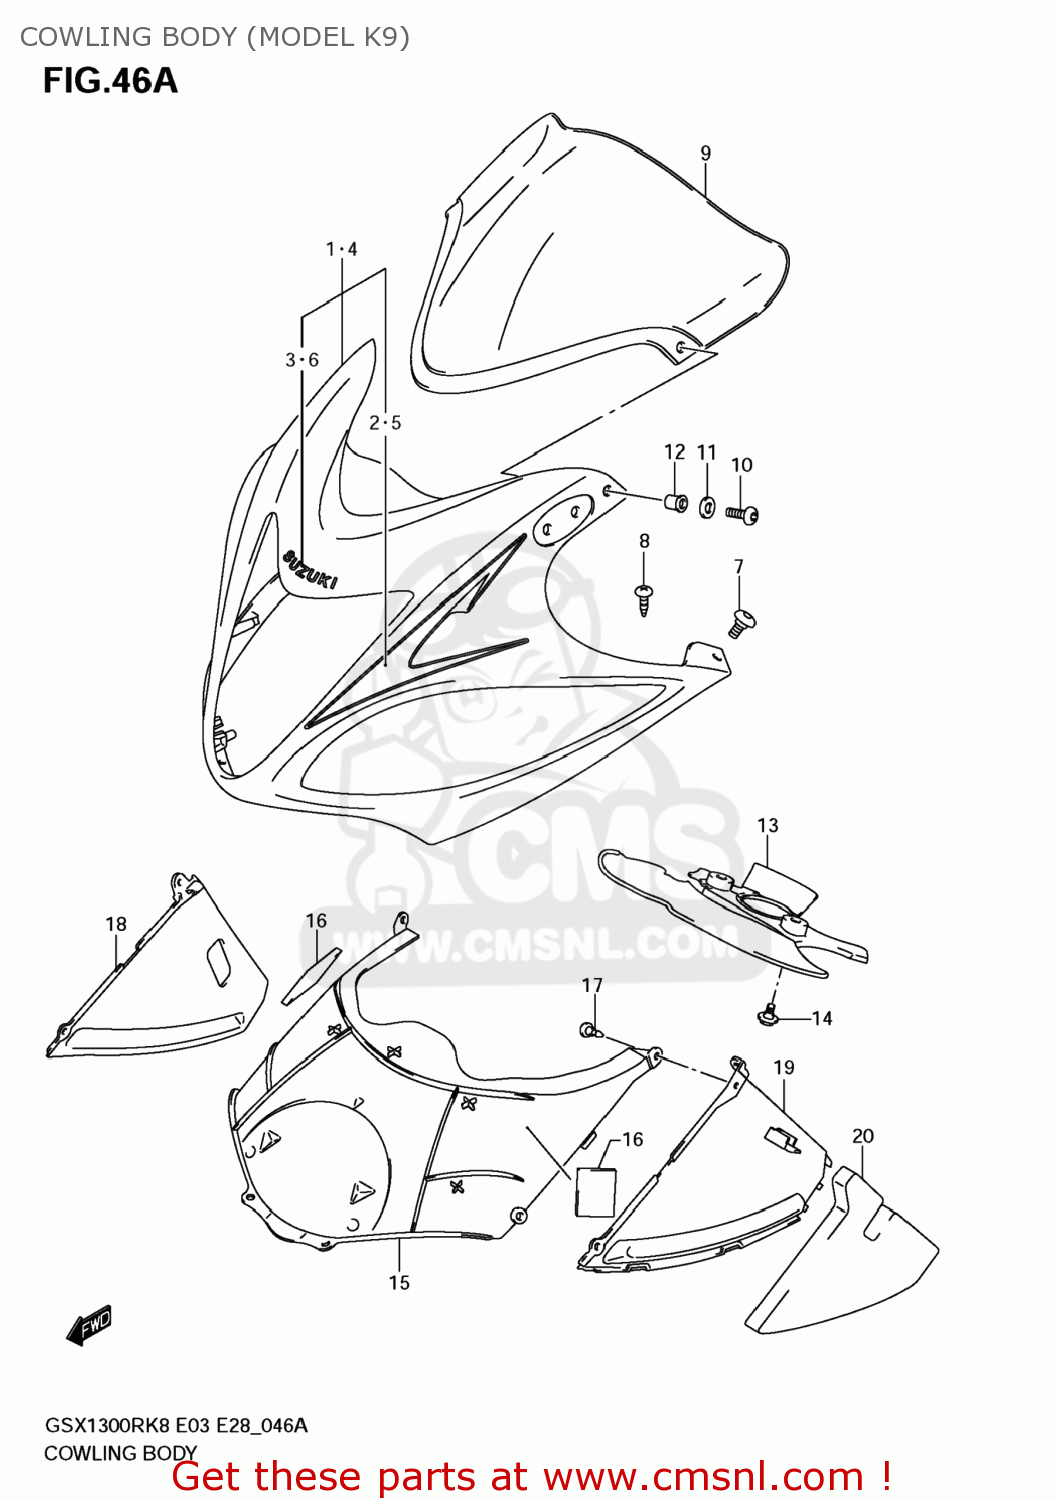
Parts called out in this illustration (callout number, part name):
1	COWLING ASSY,BODY
2	TAPE SET,BODY COWL
3	EMBLEM
4	COWLING ASSY,BODY
5	TAPE SET,BODY COWL
6	EMBLEM,SUZUKI
7	SCREW(5X16)
8	SCREW
9	WINDSCREEN
10	SCREW(5X14)
11	WASHER
12	NUT
13	COVER,LWR BRACKET
14	BOLT
15	COVER,BODY COW
16	COVER,HARNESS
17	CLIP(BLACK)
18	COWLING,UNDER INNER,R
19	COWLING,UNDER INNER,L
20	CUSHION,INNER COWL,L
